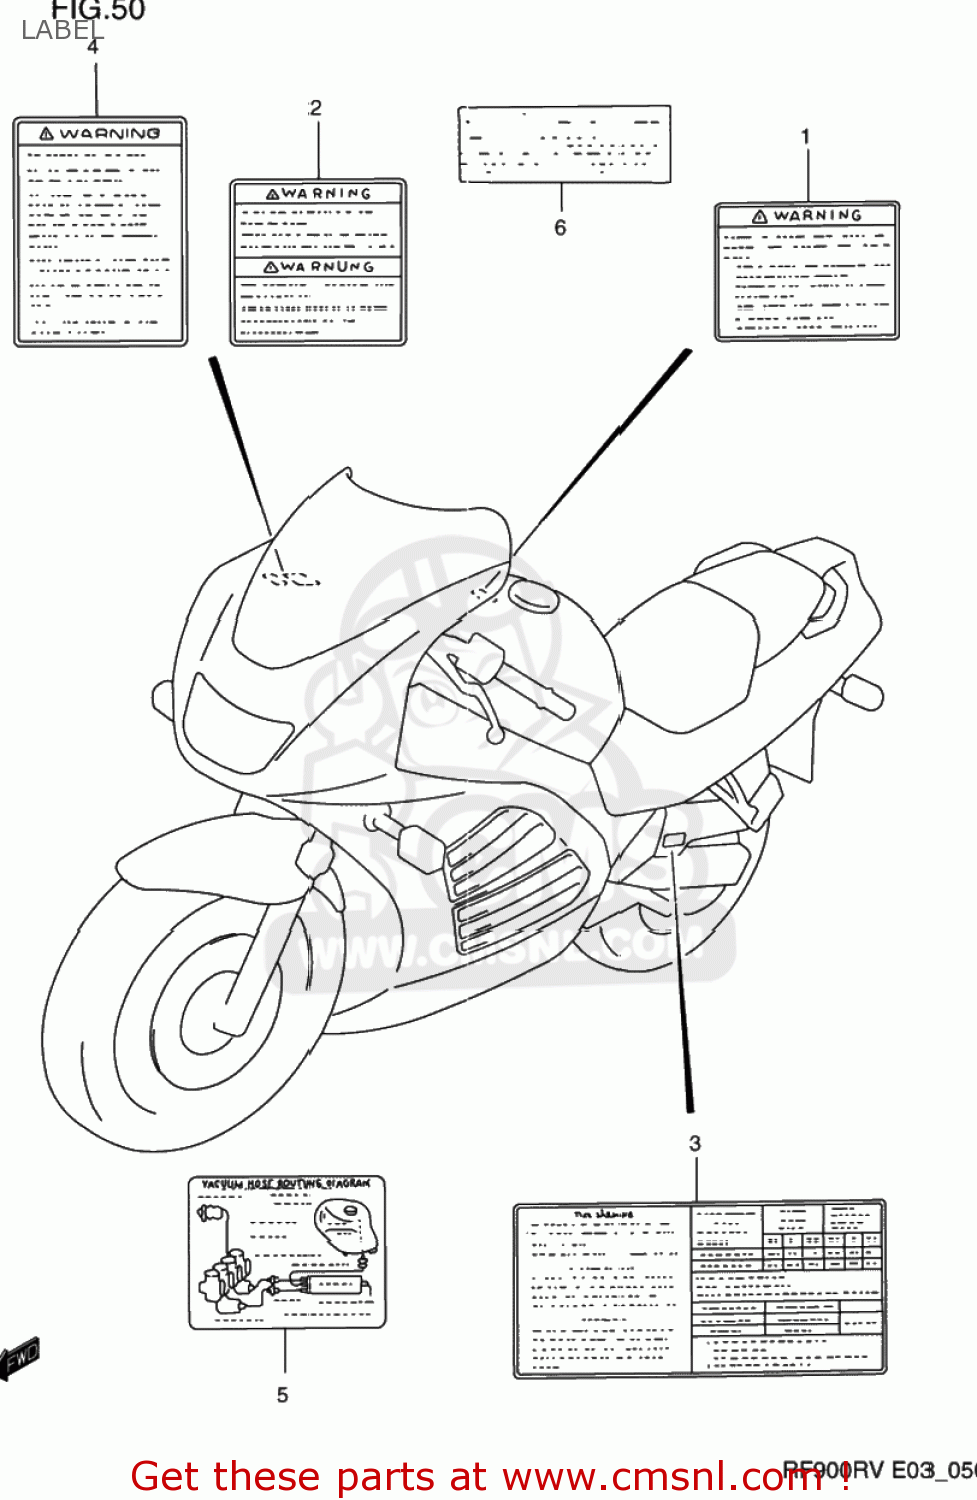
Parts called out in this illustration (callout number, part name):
1	LABEL
2	LABEL (WARNING)
3	LABEL (TIRE INFORMATION)
4	LABEL (WARNING SCREEN)
5	LABEL (VACUUM HOSE ROUTING)
6	LABEL (MANUAL NOTICE)
7	OWN MAN RF900RR
